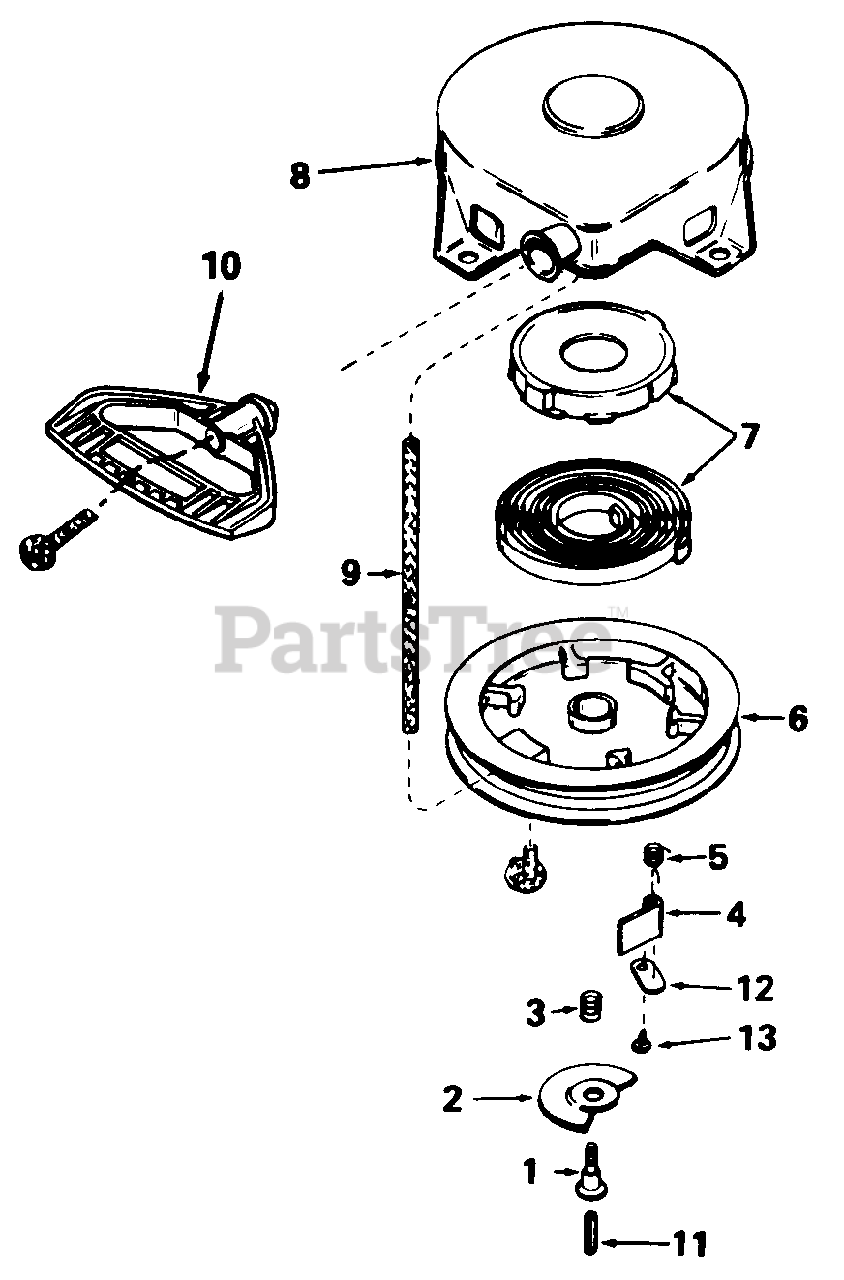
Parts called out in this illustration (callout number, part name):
1	Screw, Retainer
3	Spring, Brake
4	Dog, Starter
5	Spring, Dog
7	Spring & Keeper Ass'y.
8	Housing Ass'y., Starter
9	Rope, Starter
10	Handle, Mitten Grip (Not Included With Starter)
11	Pin, Centering
12	Retainer, Dog
13	Screw, No. 6 x 5/16
